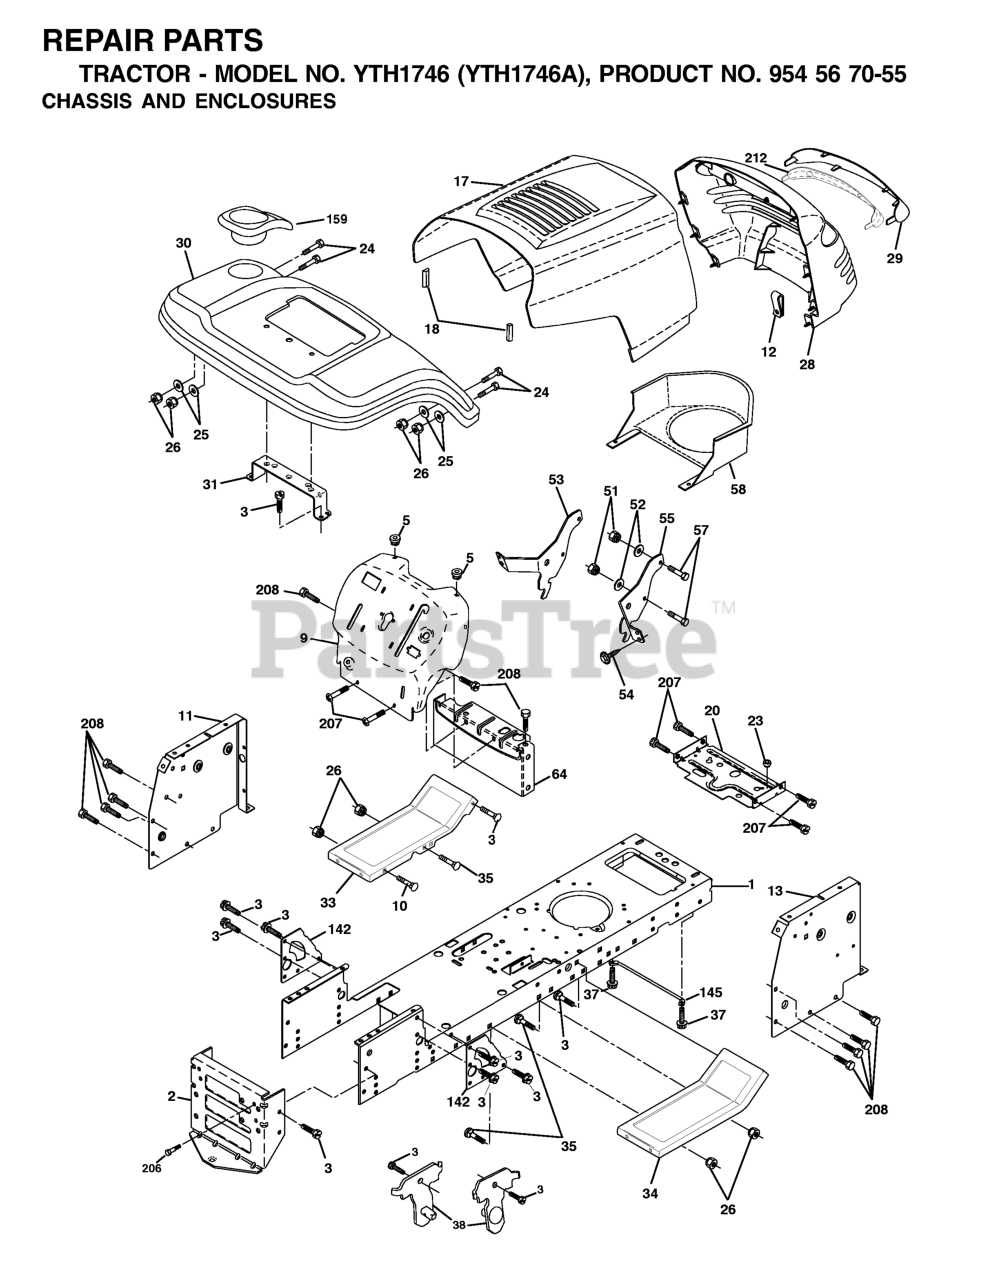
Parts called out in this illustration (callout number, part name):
2	DRAWBAR
3	SCREW 3/8-16X3/4
5	BUMPER.RUBBER.HOOD
9	DASH SLKSCR
10	BOLT D
11	PANEL DASH LH
13	PANEL ASM, DASH RH
17	HOOD ASM.
18	BUMPER HOOD T
20	PLATE MTG
23	BUSHING.SNAP.NYL.BLK.
25	WASHER
26	NUT
28	GRILLE ASM
29	LENS
31	BRACKET FENDER
33	FOOT REST LH
34	FOOTREST RH
37	Screw 5/16-18 x 1/2 Hex, Self Tapping 5/16-18 x 1/2
38	BRACKET
51	LOCKNUT.NYLOC.1/4-20
53	BRACKET.GRILLE.LH
54	SCREW.HEX.WS.HD.8-18 X 7/8
57	BOLT
58	AIR DUCT P/L/LT
64	DASH LOWER
142	PLATE
145	ROD PIVOT CHASSIS/HOOD
206	SHOULDER BOLT 5/16-18TT
207	SCREW, 5/16-18 X 1/2
208	SCREW 3/8-16X1/2
212	REPL BY 532 1745-03
